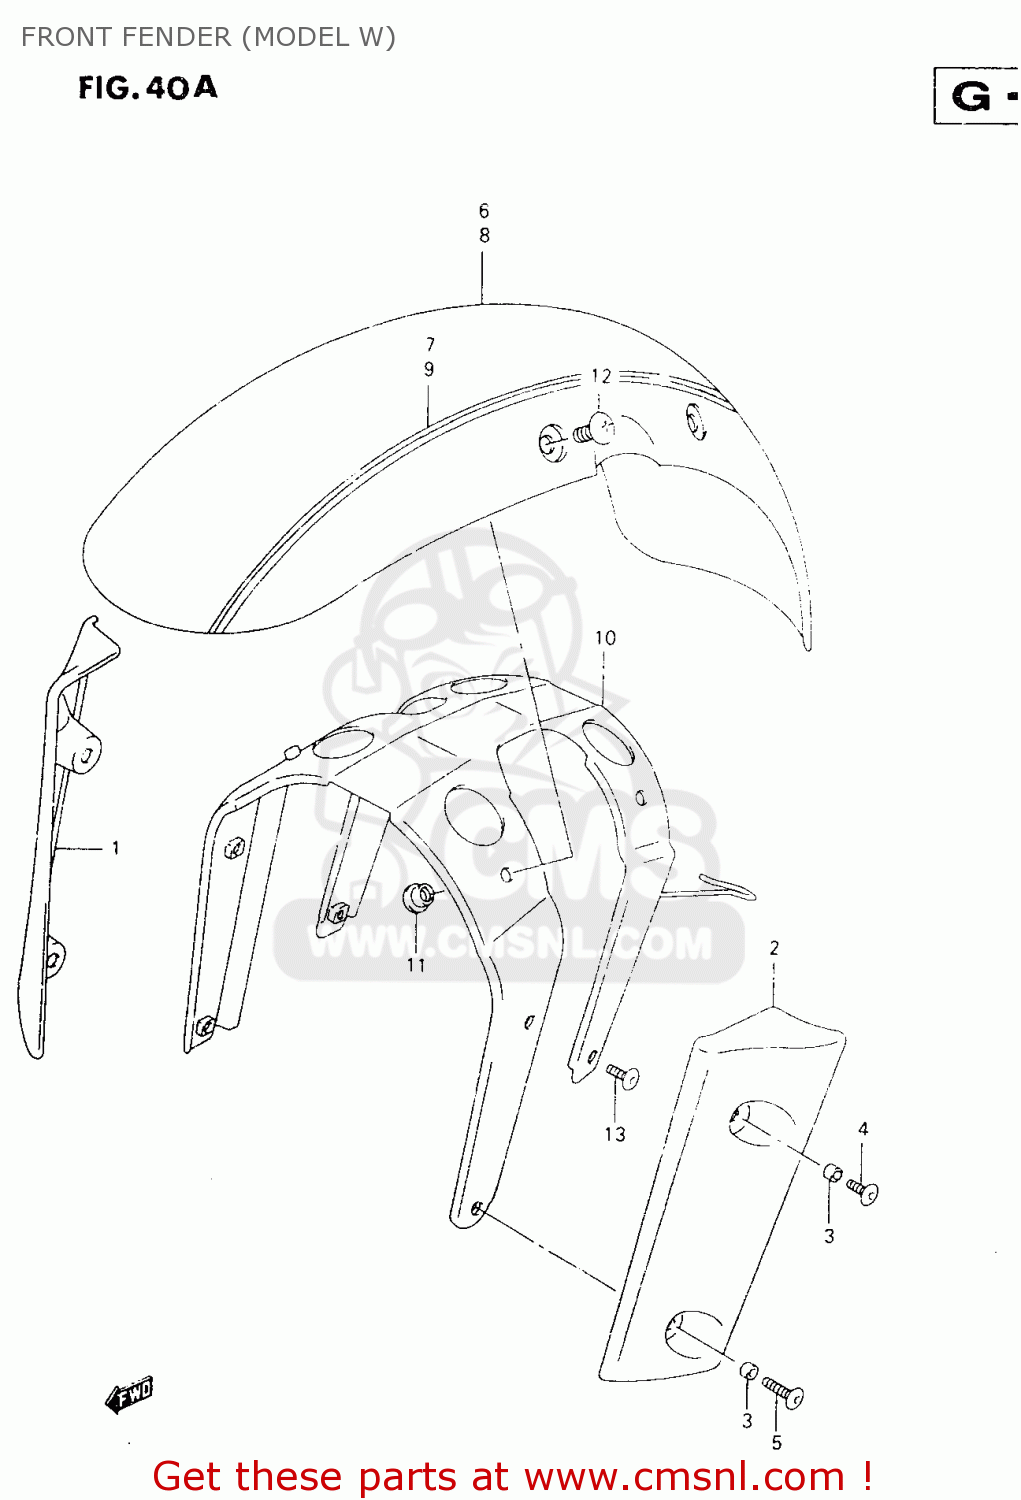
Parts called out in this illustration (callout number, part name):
1	COVER,FR FORK SIDE,R
2	COVER,FR FORK SIDE,L
3	SPACER(6.1X8X3.5)
4	SCREW(6X12)
5	SCREW(6X20)
6	FENDER,FR
7	TAPE SET,FR FENDER
8	FENDER,FR
9	TAPE SET,FR FENDER
10	BRACE,FR FENDER
11	NUT
12	SCREW(6X12)
13	SCREW(6X16)
